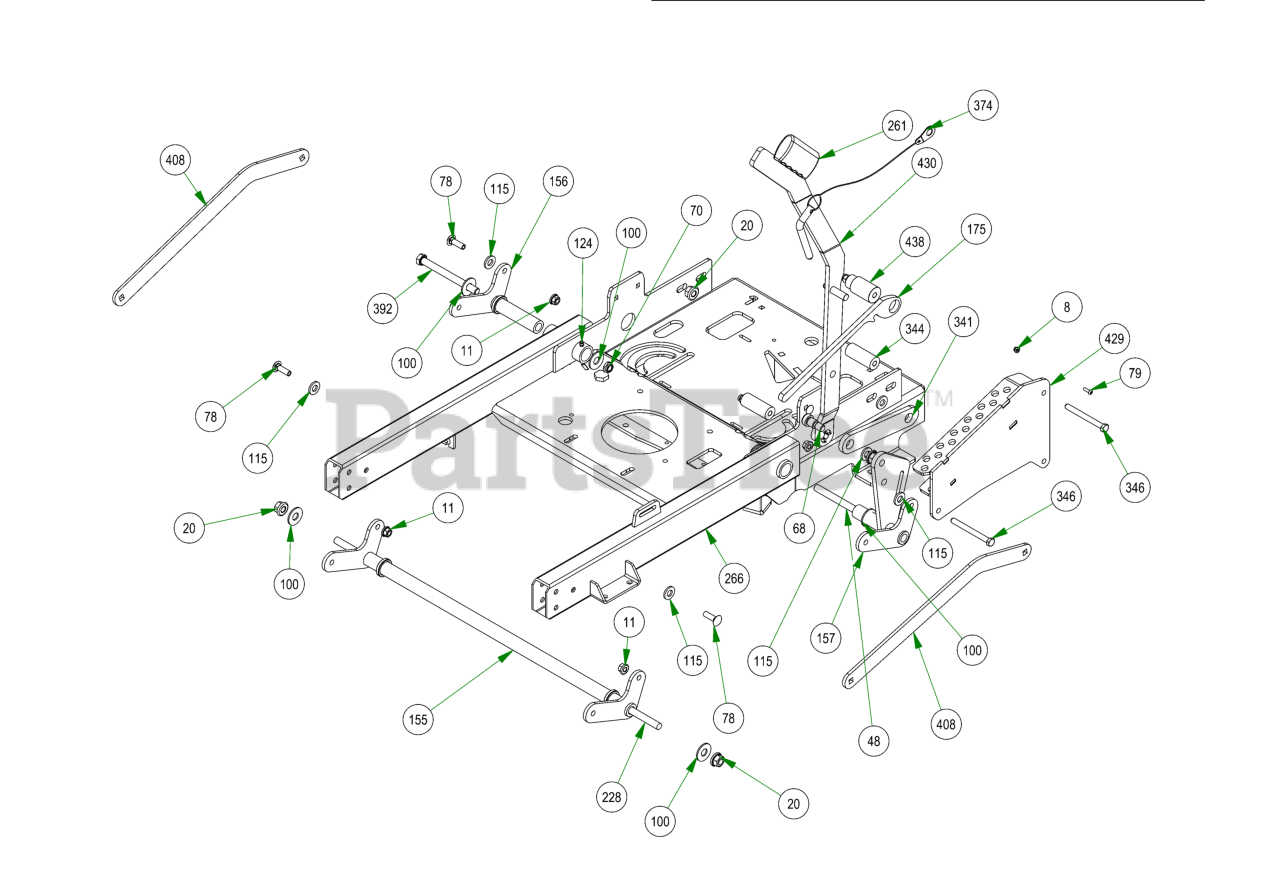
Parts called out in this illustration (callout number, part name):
8	10-24 NYLON INSERT LOCKNUT ZINC
9	3/8-16 NYLON INSERT LOCKNUT ZINC
11	3/8-16 NYLON INSERT FLANGE LOCKNUT (GR.F) ZINC
19	5/16-18 NYLON INSERT FLANGE LOCKNUT ZINC
20	1/2-13 NYLON INSERT FLANGE LOCKNUT ZINC
31	1 1/2 x 3 Frame Plug
40	Pillow Block Kit
40.1	Pillow Block MZ
40.3	Pillow Block Strap
48	1/2-13 X 6 1/2 HEX CAP SCREW (GR.5) ZINC
68	5/8 X 5/8 SOCKET SHOULDER BOLT ZINC YELLOW
70	1/2-13 NYLON INSERT JAM LOCKNUT ZINC
78	3/8-16 X 1-1/4 CARRIAGE BOLT ZINC
79	10-24 X 5/8 BUTTON SOCKET CAP SCREW 18-8 STAINLESS STEEL
98	5/16-18 X 1 CARRIAGE BOLT (GR.8) ZINC
100	1/2 F/W USS (1-3/8" OD) ZINCC
115	.505 ID X 1.000 OD X .125 THICK FLAT WASHER NYLON
116	Revolt Cotter Pin for 7/8" to 1" shank
124	1/4 DRIVE-TYPE STRAIGHT GREASE FITTING (NO BALL) ZINC
155	Revolt Front Actuator Bar Weldment 2020 36" Black
156	Revolt Rear Actuator Bar Weldment RH 2020 36" Black
157	Revolt Rear Actuator Bar Weldment LH 2020 36" Black
175	2019 Stand On Deck Lever Lock
227	2018 Maverick Turnbuckle (Top Link)
228	2020 36 Stand On Turnbuckle Rod
238	Revolt Fuel Line Assembly
238.1	1/4 Fuel Line
238.2	1/4 Fuel Hose Clamp
261	2019 Stand On Lift Grip
266	2020 36" Stand On Frame
274	2019 Stand On Gas Tank Strap
341	2023 lever secondary linkage
344	Stand On Spacer 2.5''
346	3/8-16 X 3-3/4 HEX CAP SCREW (GR.5) ZINC
354	.627 ID X .753 OD X .500 LGTH X 1.000 FLG OD X .094 FLG THICK
374	2023 stand on Height Adj Pin
384	2023 Revolt Deck Hight decal
385	2023 Revolt side hight plate decal
392	1/2-13 X 5 1/2 HEX CAP SCREW (GR.5) ZINC
408	2023 SD-36 Stand-on Actuator Linkage
429	2023 Stand On Outer Adjustment Plate weldment
430	2023 Stand On SD Lift Lever Weldment
438	Stand On Spacer 2.5'' With shoulder
441	3/8-16 X 2-1/2 HEX CAP SCREW (GR.5) ZINC
